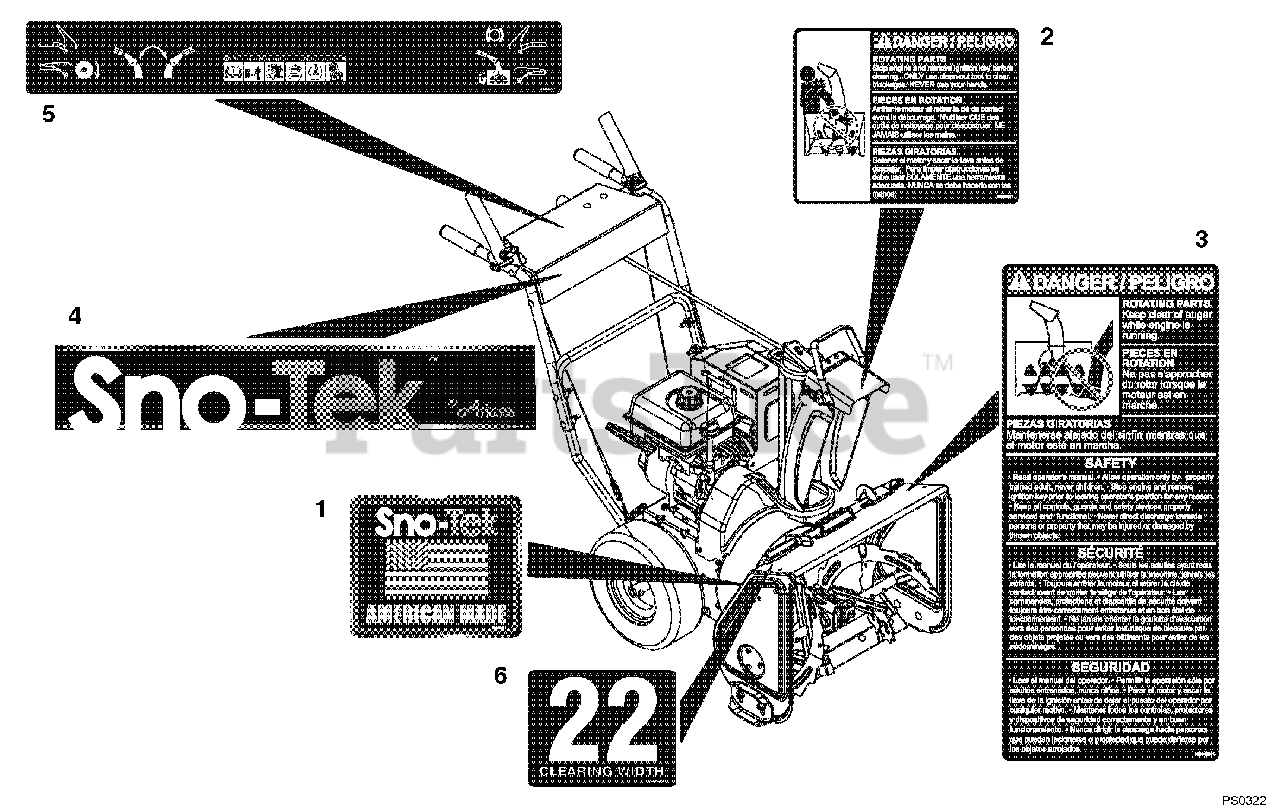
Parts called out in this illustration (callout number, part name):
1	DECAL, SNO-TEK - AMERICAN MADE
2	DECAL, DANGER - ROT. PARTS
3	DECAL, DANGER
4	DECAL, DASH - SNO-TEK
5	DECAL, CTRL PANEL, SINGLE SPD
6	DECAL, HOUSING SNO-TEK 22
